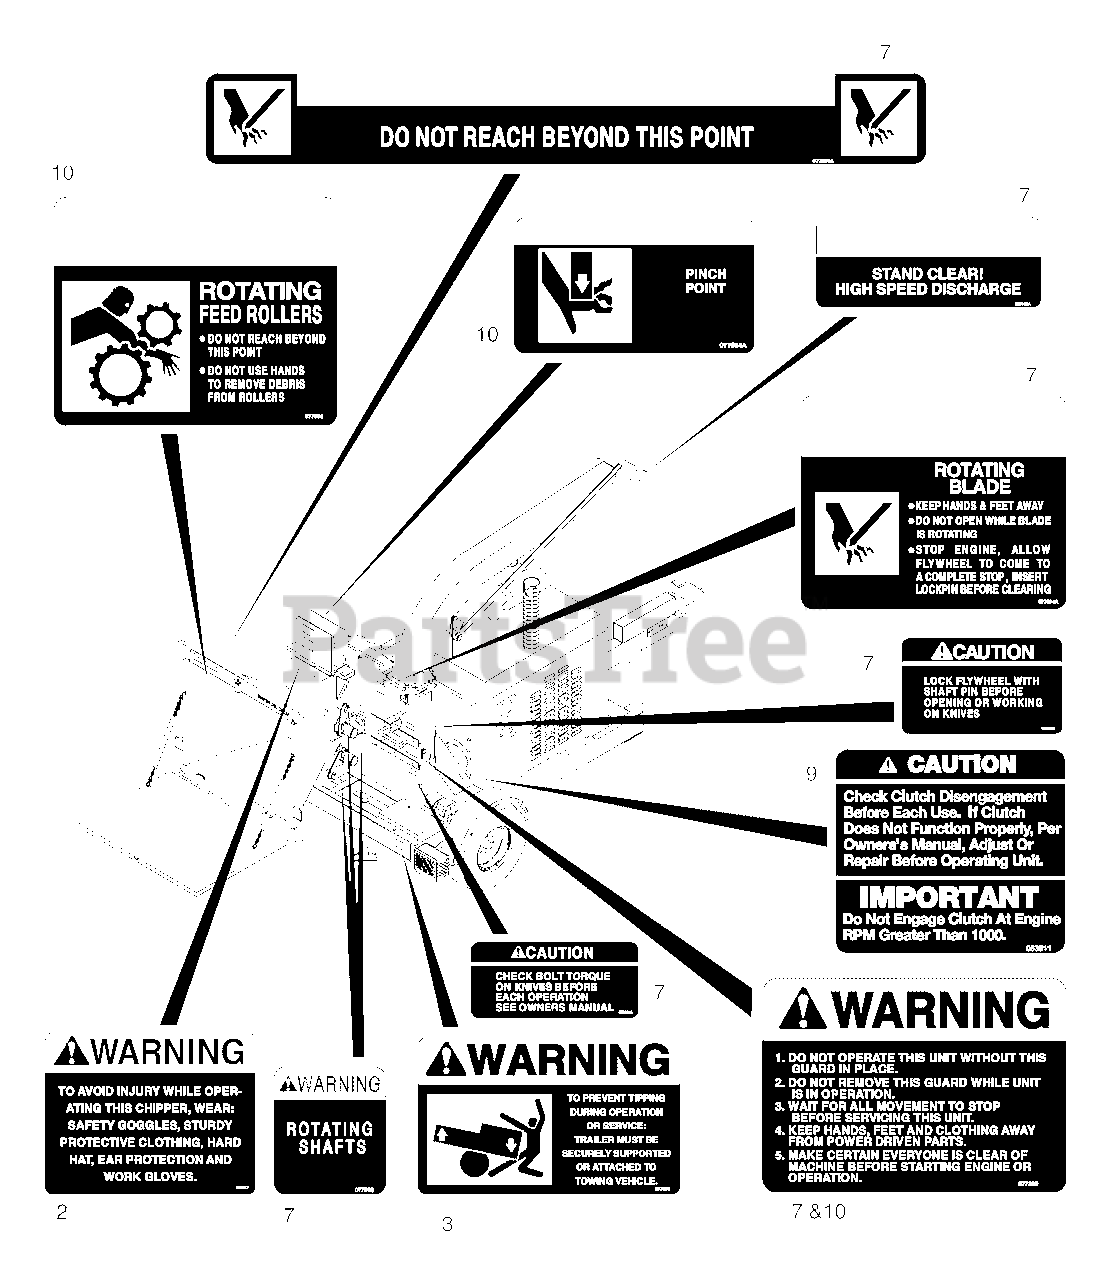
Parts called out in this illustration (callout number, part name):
2	Decal-WARNING Protective
3	Decal-WARNING-Tipping
7	Decal Set-Large Chippers
9	Decal-Clutching Instruction
10	Decal Set
